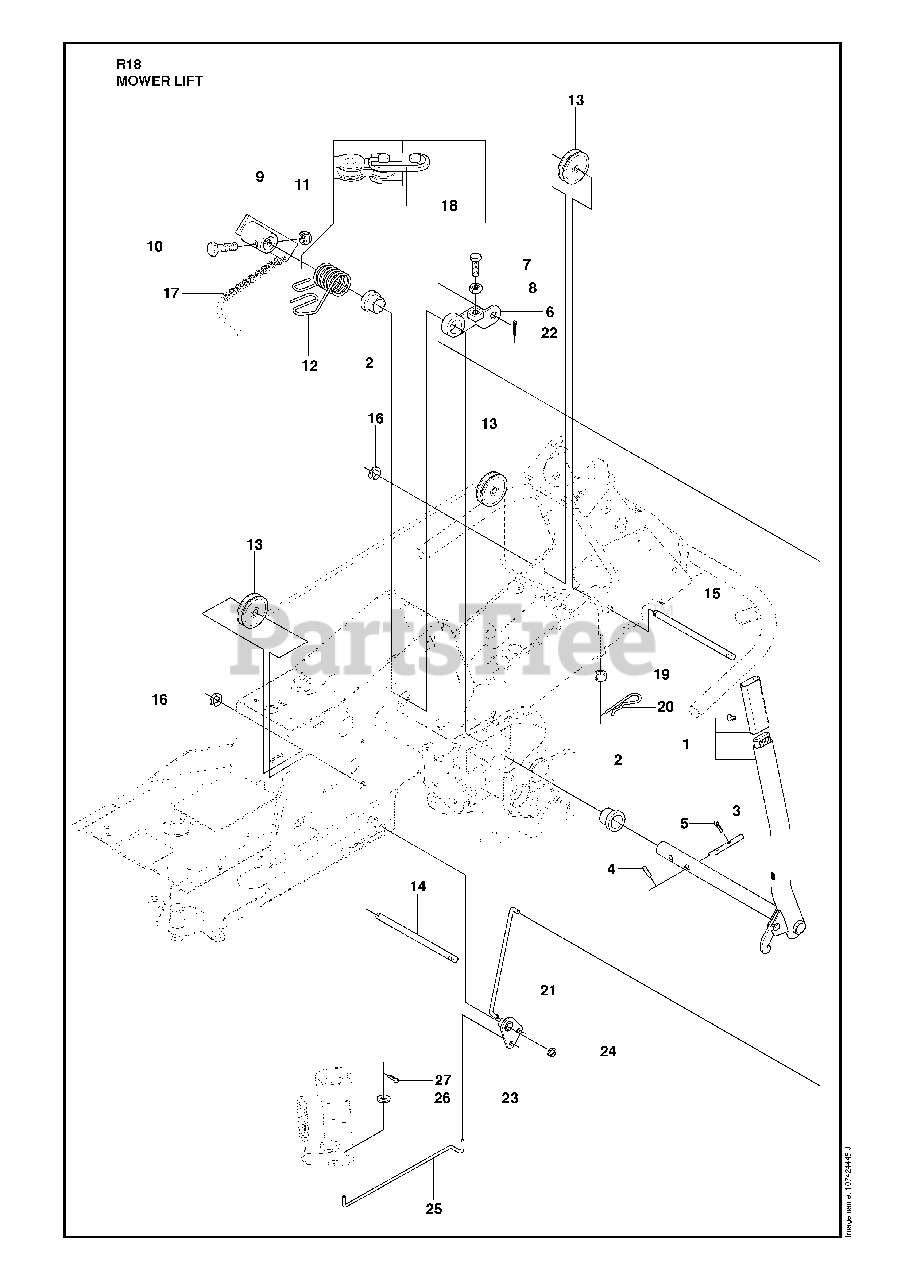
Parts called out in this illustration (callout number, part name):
1	LIFTING LEVER ASSY
2	BEARING FLANGE
3	RP PIN
6	LEVER CLUTCH
8	NUT
9	LIFTING ARM
11	Lock Nut, Fiber M12 DIN 985 Z/P
21	CONNECTION ROD
24	RETAINING RING
25	CONNECTION ROD
